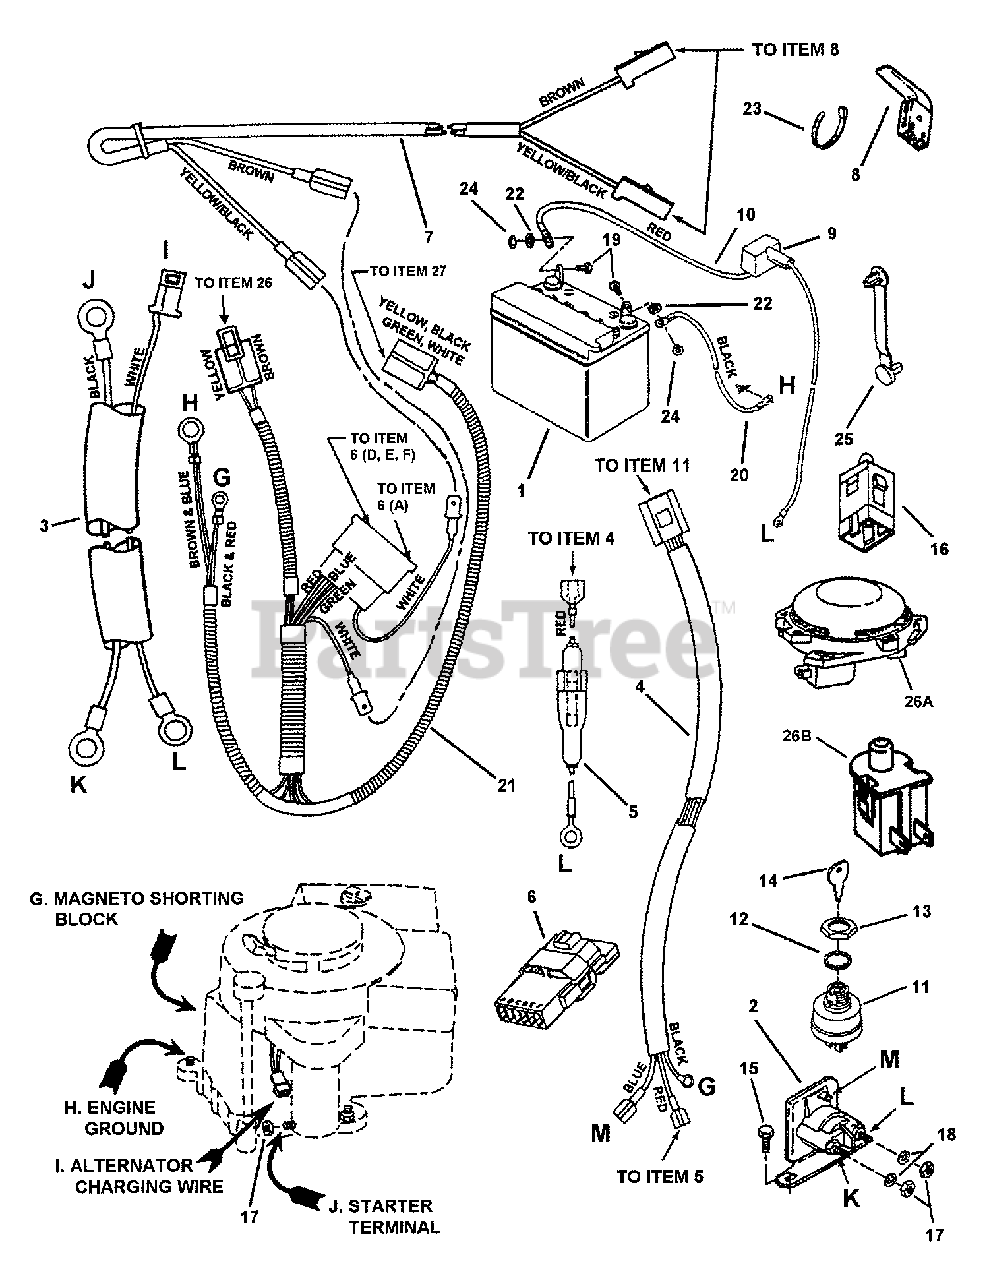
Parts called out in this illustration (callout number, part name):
1	KIT, Battery, 12 Volt, 220CCA, Dry Charge
2	SOLENOID, Super-Trombetta
3	HARNESS, Starter Wiring (Briggs Engines)
4	HARNESS, Ignition Wiring (Briggs Engines)
5	HOLDER, Fuse (Includes Fuse)
6	INTERLOCK MODULE, Briggs
7	HARNESS (Deck Interlock Wiring)
8	SWITCH, Deck Interlock (NO)
9	COVER, Battery Cable
10	WIRE, Positive (Red, 17 long)
11	SWITCH, Ignition, 4 Terminal, Indak
12	WASHER, 5/8 Internal Tooth Lock
13	NUT, 5/8-32 Hex
14	IGNITION KEY, Pair
14	KEYS, Blister Pk (KIDS+MWRS DON'T MIX) English/French (set of two, one coated)
15	HHCS, 1/4-20 X .500, GR5 Zinc/Clear Hex Washer HD Taptite
16	SWITCH, Operator Presence Control (OPC) Traction (NC/NO)
17	NUT, 1/4-20, Zinc/Clear
18	WASHER,1/4 Internal Tooth Lock
19	HHCS, 1/4-20 X 0.625, GR5 Zinc/Clear
20	WIRE, Negative, Black (15 long)
21	HARNESS, Operator Presence Control (OPC) Wire
22	RETAINER, 1/4 Bolt
23	CABLE TIE, 7"
24	NUT, 1/4-20 Hex Center Lock, GR 5 or B
25	CABLE TIE, 3.19 long
26A	SWITCH, Seat (NC)
26B	SWITCH, Seat (NC)
